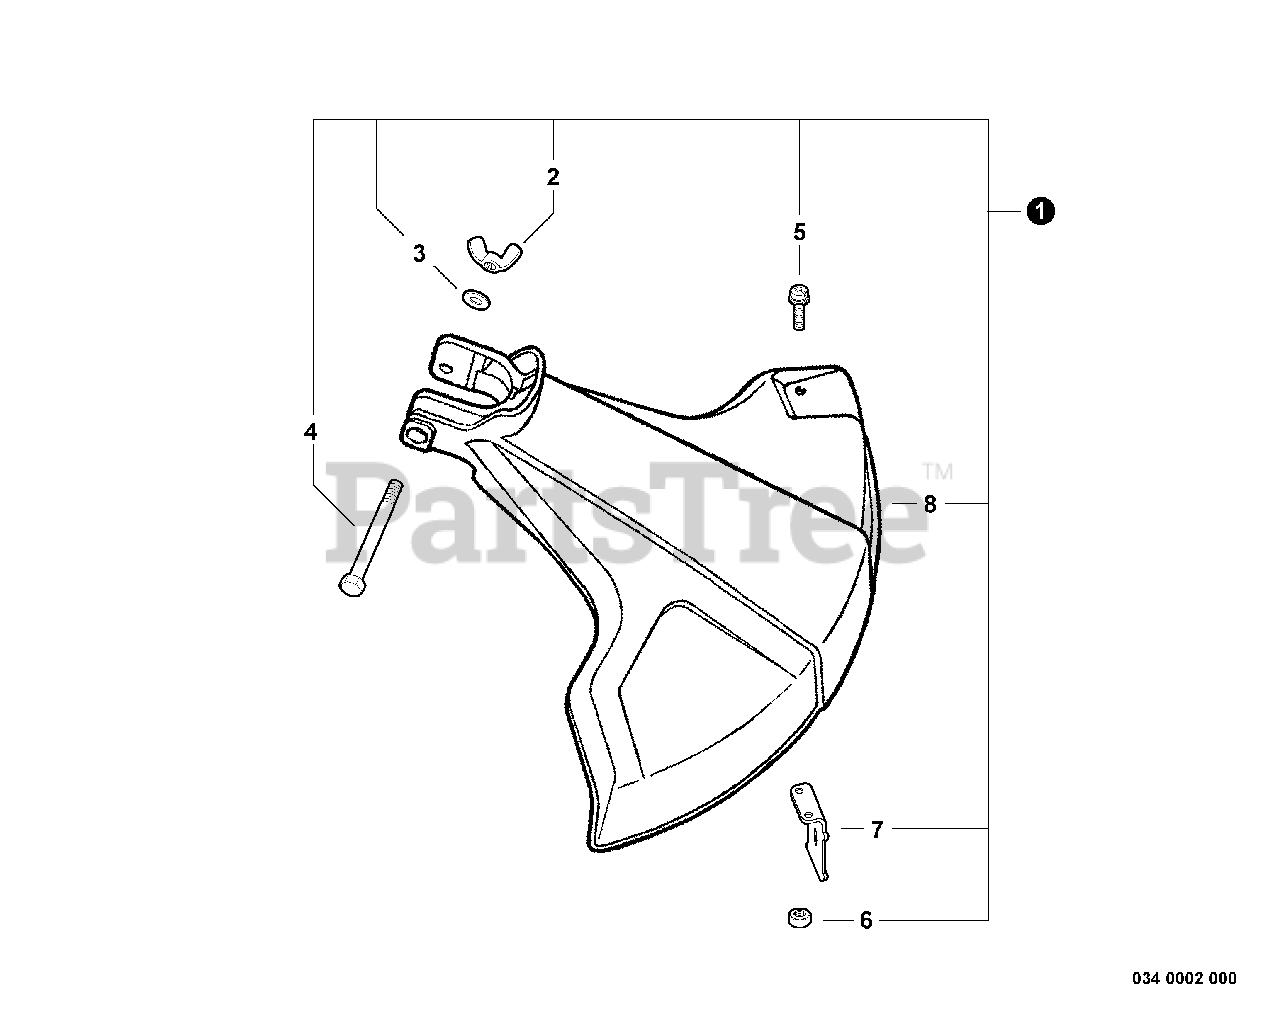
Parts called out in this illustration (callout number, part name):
1	SHIELD ASSY
2	NUT, WING 1/4"-20
3	WASHER, 1/4"
4	BOLT 1/4"-20×2"
5	SCREW 5×16
6	NUT M5
7	CUTTER, LINE
8	SHIELD, DEBRIS
